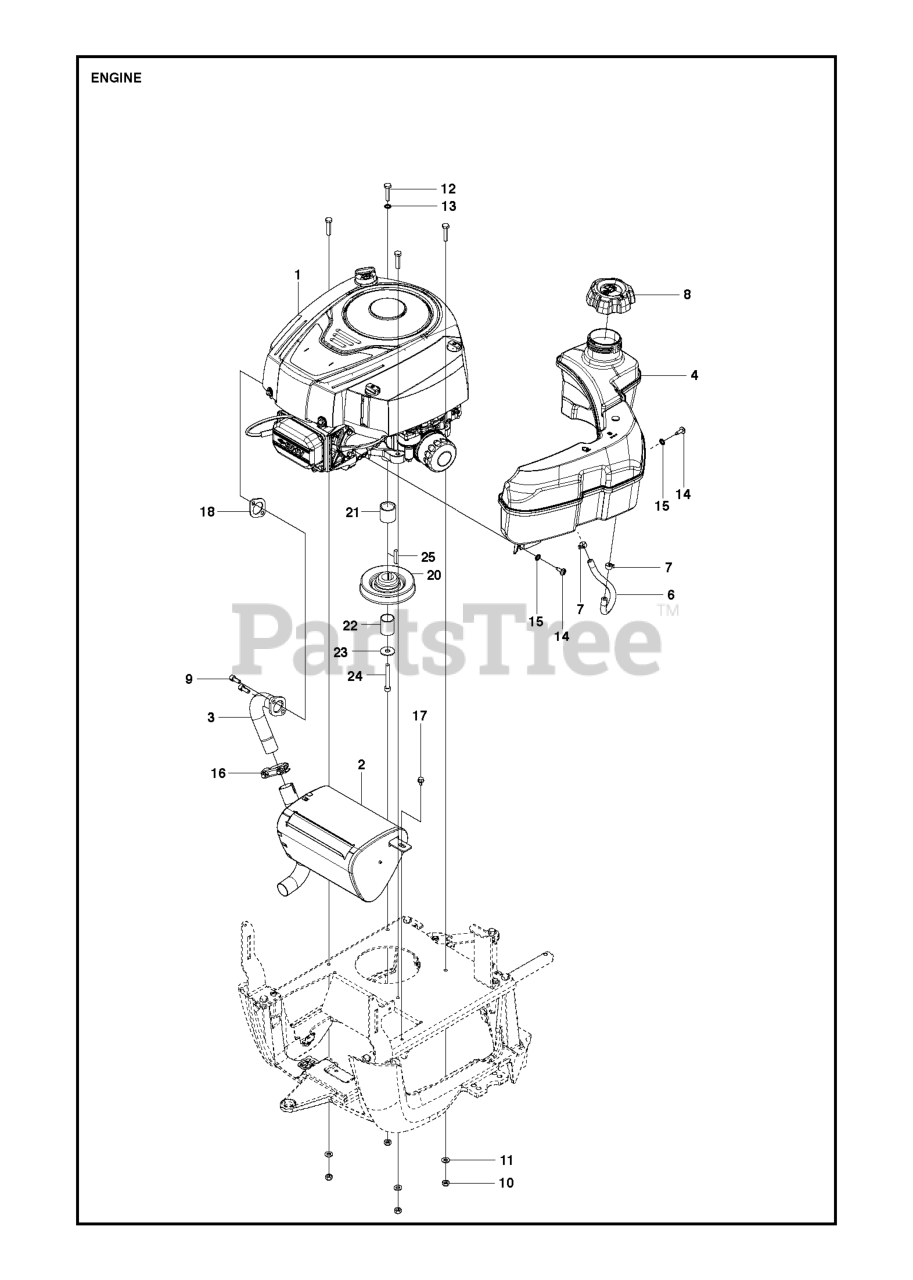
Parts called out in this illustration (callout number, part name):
2	MUFFLER ASSY
8	CAP.FL.R.3'N/CARB.H.CROWN.498
10	LOCKNUT M8
11	WASHER BRB 8.4X17
16	CLAMP
21	SPACING SLEEVE
